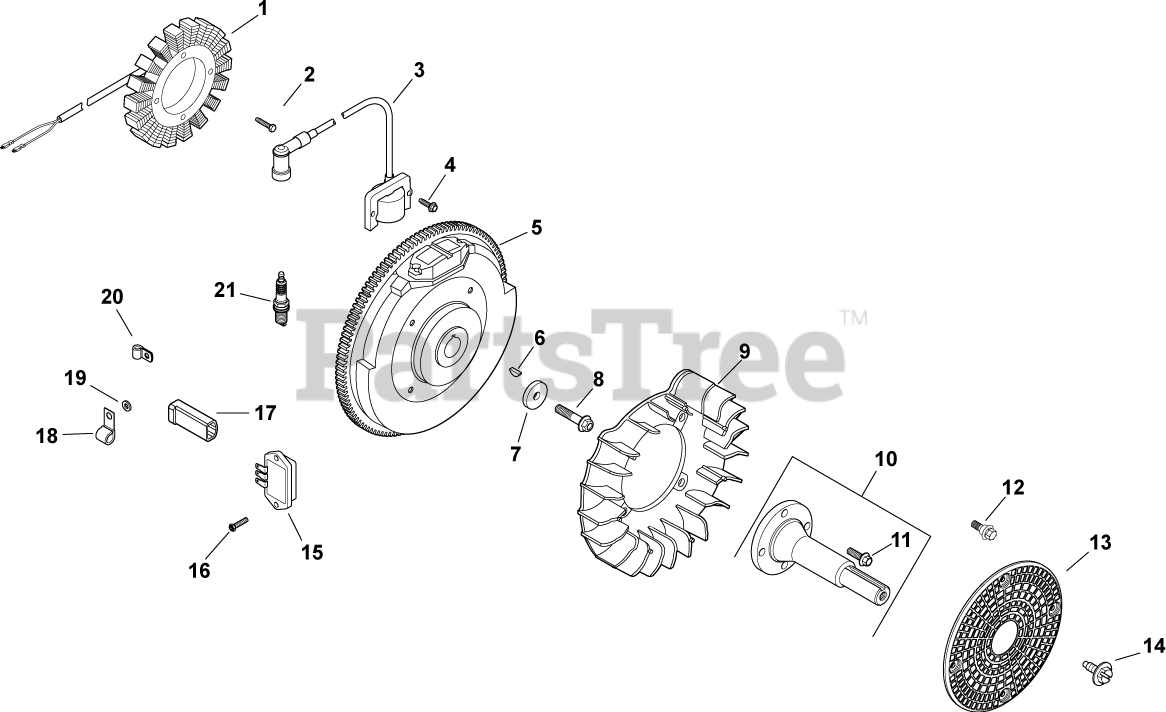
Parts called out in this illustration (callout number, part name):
1	KIT, 25 AMP STATOR ASSY.
2	SCREW, THD FROM M5X0.8X30
3	KIT, MODULE IGNTN (CDI FIXED)
4	SCREW, FLG THD FRM M5X.8X20-(#25086399S)
6	KEY, 3/16" X 5/8"
7	WASHER, FLAT 13/32"
8	SCREW, FLG M10X1.5X45 - (#25086361S)
9	FAN USE 24 755 253-S
10	SHAFT
11	SCREW, FLG M8X1.25X25
12	BOLT, SHOULDER
13	SCREEN, GRASS
15	REGULATOR, RECTIFIER USE 25 403 32-S
16	SCREW, HEX FLANGE HI-LO
17	CONNECTOR
18	CLIP, CABLE
19	WASHER, FLAT 1/4" (O.D. 1/2")
21	PLUG, SPARK (STD)
